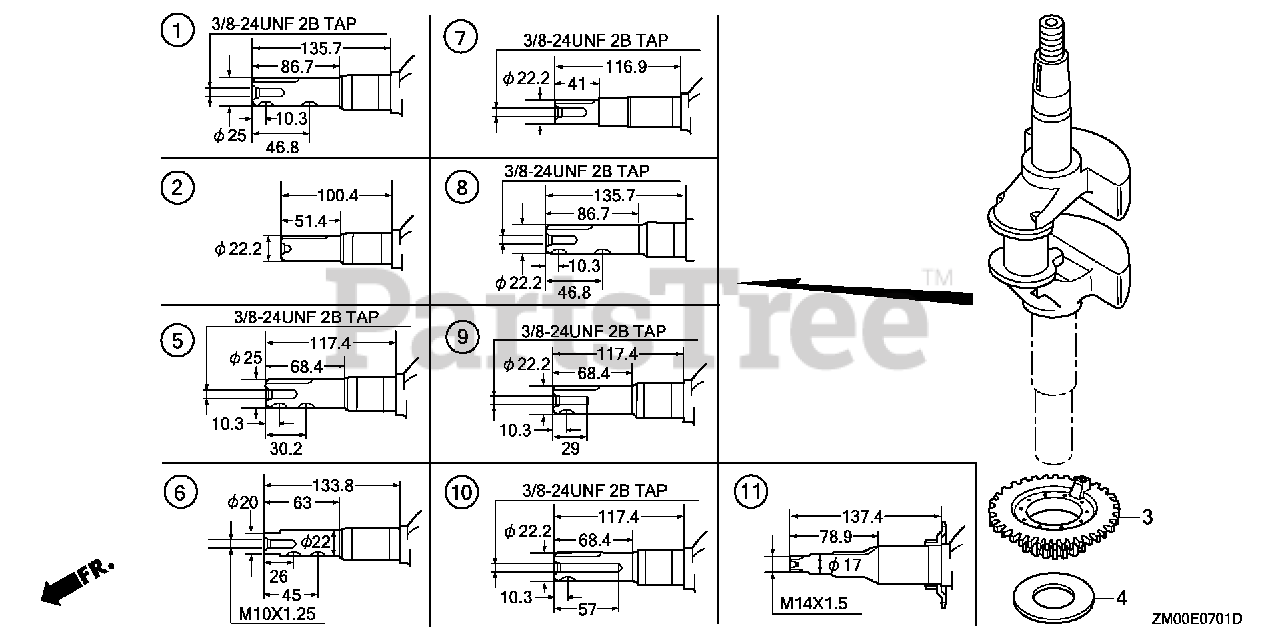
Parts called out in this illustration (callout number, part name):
3	PULLEY, TIMING BELT DRIVE
4	WASHER, THRUST
8	CRANKSHAFT
